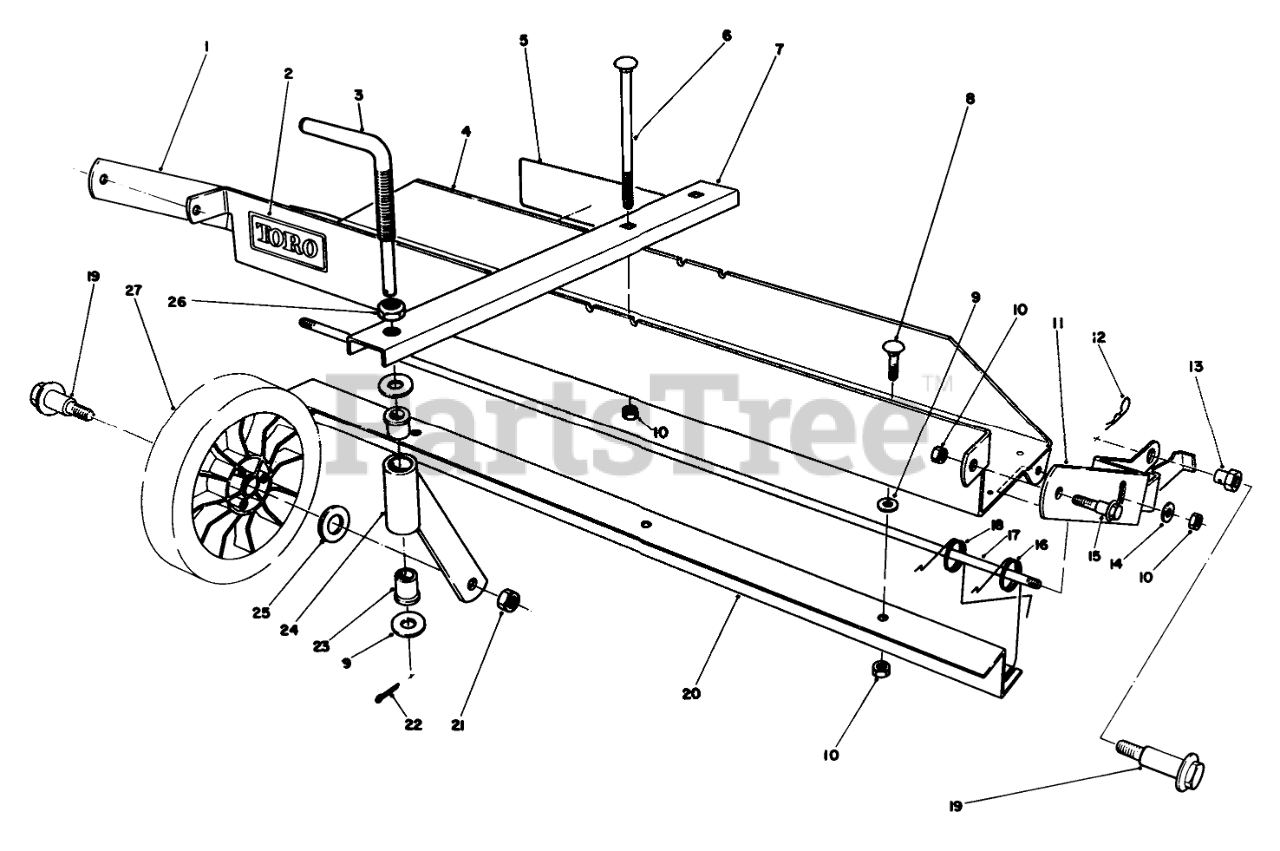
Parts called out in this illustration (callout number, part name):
1	Frame R.H.
2	Decal-Toro
3	CASTOR ADJ ROD
4	Frame-Main (Incl. Ref. #2)
5	Decal-Instruction
6	SCREW-CARR
7	Castor Frame
8	BOLT-CARR
9	WASHER-PLAIN
10	NUT-HEX, SIDE DEFORM
11	LH MTG FRAME
12	PIN-COTTER, HAIR
13	PIVOT NUT
14	WASHER-FLAT
15	BOLT-SHOULDER
16	DETHATCHER SPRING
17	SPRING SUPPORT ROD
18	DETHATCHER SPRING
19	BOLT-WHEEL
20	SPRING GUIDE STRAP
21	NUT-LOCK
22	PIN-COTTER
23	FLANGE BUSHING
24	Castor Tube & Support
25	WASHER
26	NUT-JAM
27	Wheel Assembly
